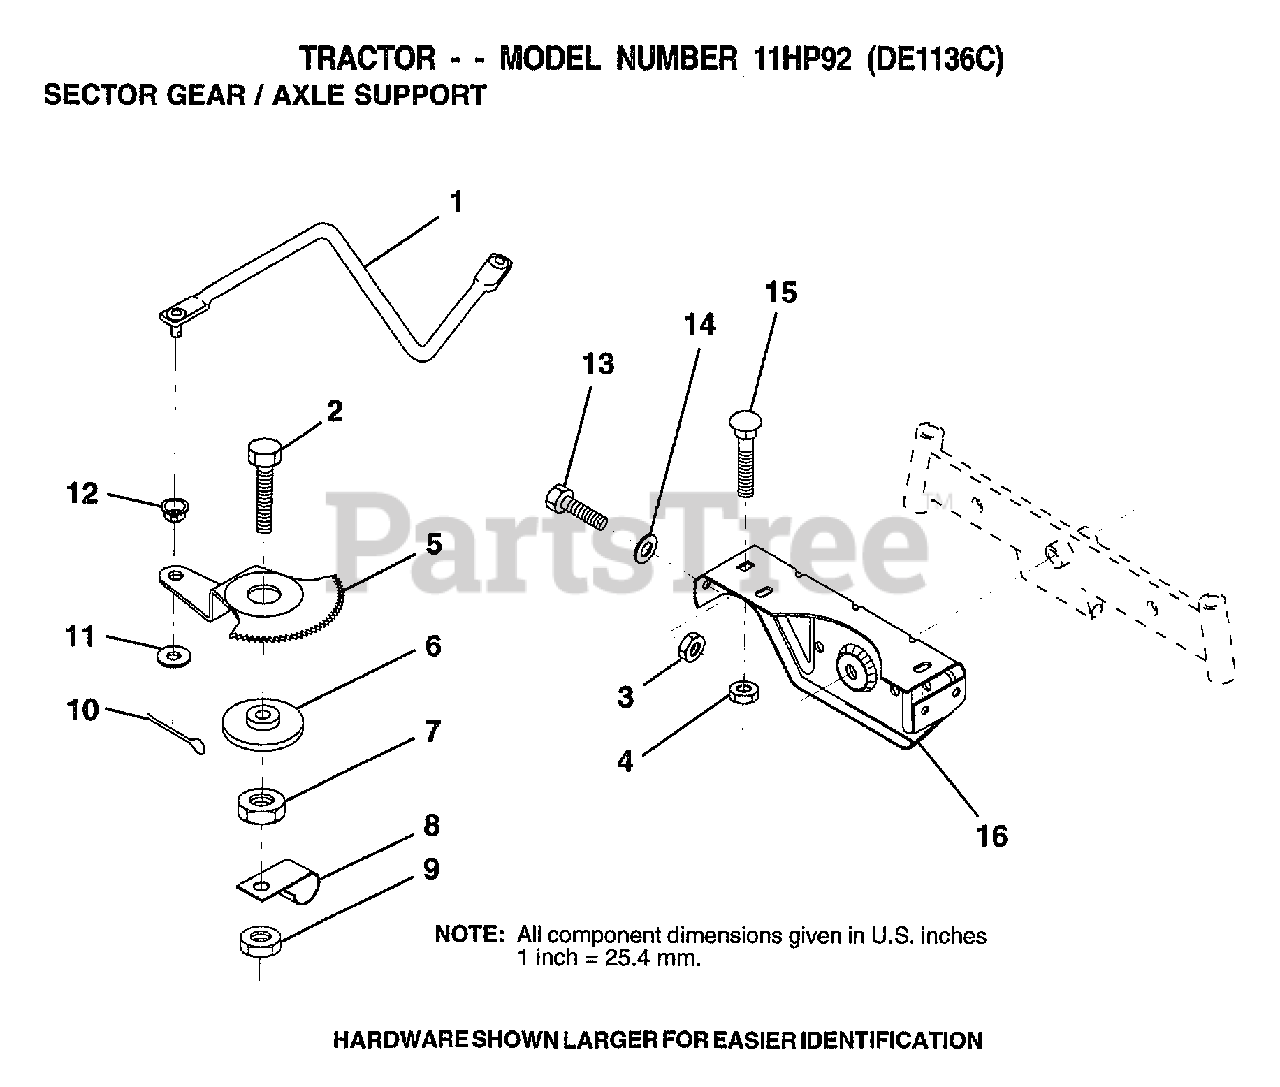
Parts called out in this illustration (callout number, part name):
1	DRAG LINK
2	"BOLT,HEX"
5	GEAR SECTOR
6	BUSHING
7	NUT
8	CLIP INSULATOR
9	NUT LTV
10	COTTER PIN
11	WASHER
12	BUSHING.DRAGLINK
13	BOLT
14	WASHER
15	BOLT
16	SUPT AXLE FRONT
